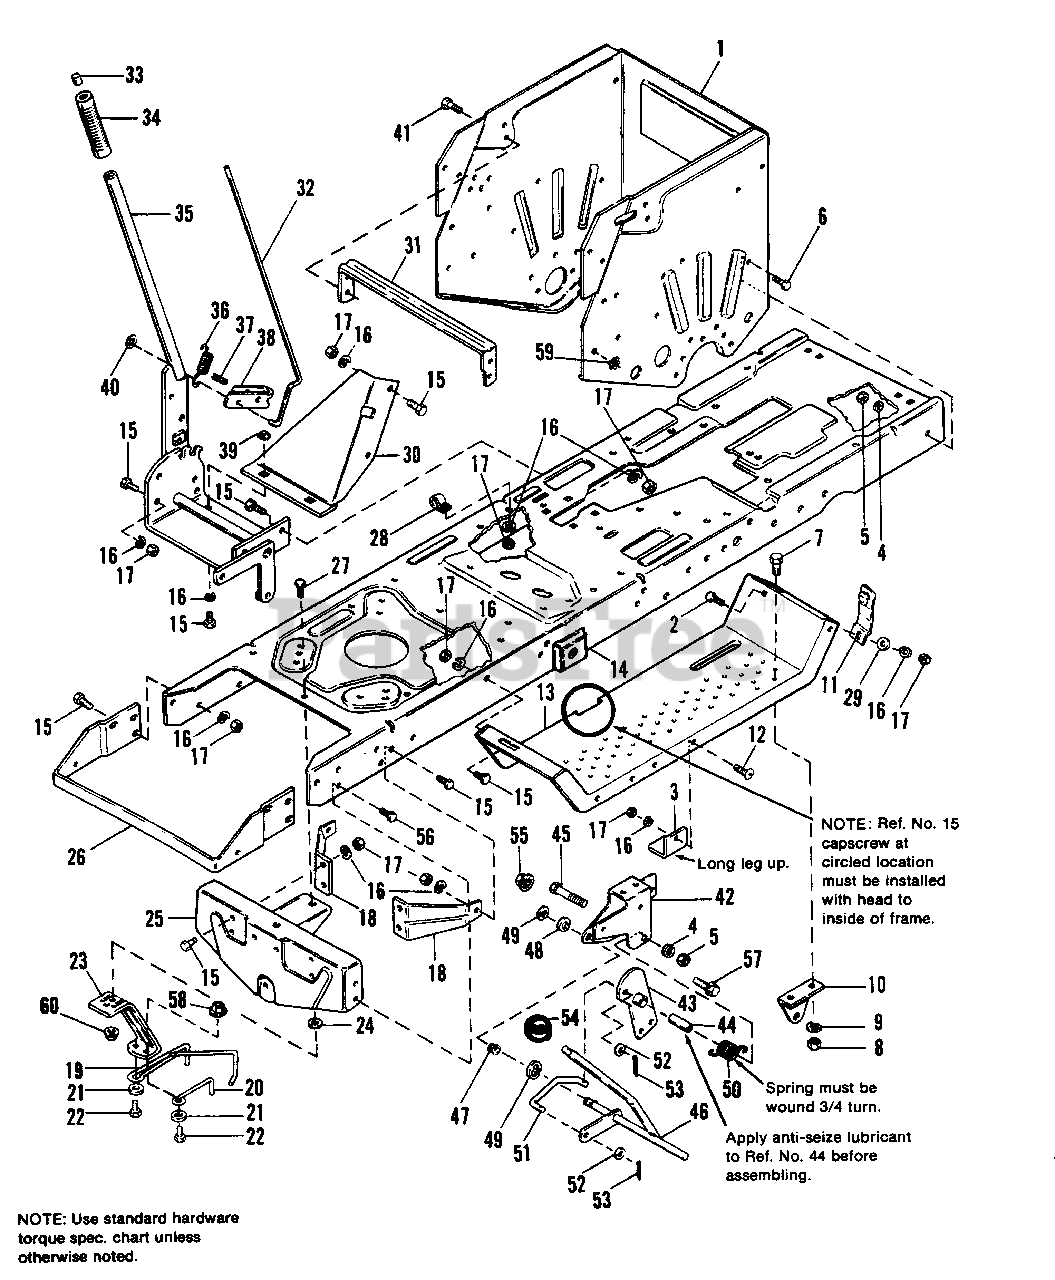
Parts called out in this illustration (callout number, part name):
1	SUPPORT, Axle Wrapper
2	BOLT, Carriage, 5/16-18 x 3/4
3	UP-STOP, Mower
4	LOCKWASHER, 3/8
5	NUT, Hex, Full, 3/8-16
6	CAPSCREW, Hex, 3/8-16 x 3/4
7	CAPSCREW, Hex, 1/4-20 x 5/8
8	NUT, Hex, Full, 1/4-20
9	LOCKWASHER, 1/4
10	SUPPORT, Clutch
11	LATCH Assy.
12	SCREW, Truss Hd., Slotted, 5/16-18 x 3/4
15	CAPSCREW, Hex, 5/16-18 x 3/4
16	LOCKWASHER, 5/16
17	NUT, Hex, Full, 5/16-18
18	BRACE, Axle Support
21	WASHER, Plain, 1/4
22	CAPSCREW, 5/16-18 x 7/8
23	SUPPORT, Belt Guide
24	WASHER, Plain, 11/32
25	SUPPORT ASSY., Axle
26	SUPPORT, Hood
27	CAPSCREW, Hex, 5/16-18 x 1
29	WASHER, 5/16 Std.
30	BRACE, Lift
31	BRACE, Seat
34	GRIP
35	LEVER ASSY., Lift
37	PIN, Spring, 3/8 x 1
38	LATCH, Lever
39	NUT, Speed, 5/16-18
41	SCREW, Taptite, 5/16-18 x 1/2
42	BRACKET, P.T.O.
43	ARM ASSY., P.T.O. Rod
45	CAPSCREW, Hex, 3/8-16 x 2-1/4
46	HANDLE ASSY., P.T.O.
47	BUSHING, Split
48	WASHER
49	RING, Snap
50	SPRING, Torsion
51	LINK, P.T.O.
52	WASHER
53	PIN, Cotter, 3/32 x 3/4
55	NUT, Flange, Whizlock, 1/4-20
56	SCREW, Taptite, 5/16-18 x 3/4
57	CAPSCREW, Hex, Wash. Hd., 1/4-20 x 5/8
58	LOCKNUT, Hex, Flange, 5/16-18
59	LOCKWASHER, 3/8 (Zinc Pltd.)
60	NUT, Hex Flange Whizlock, 5/16-18
